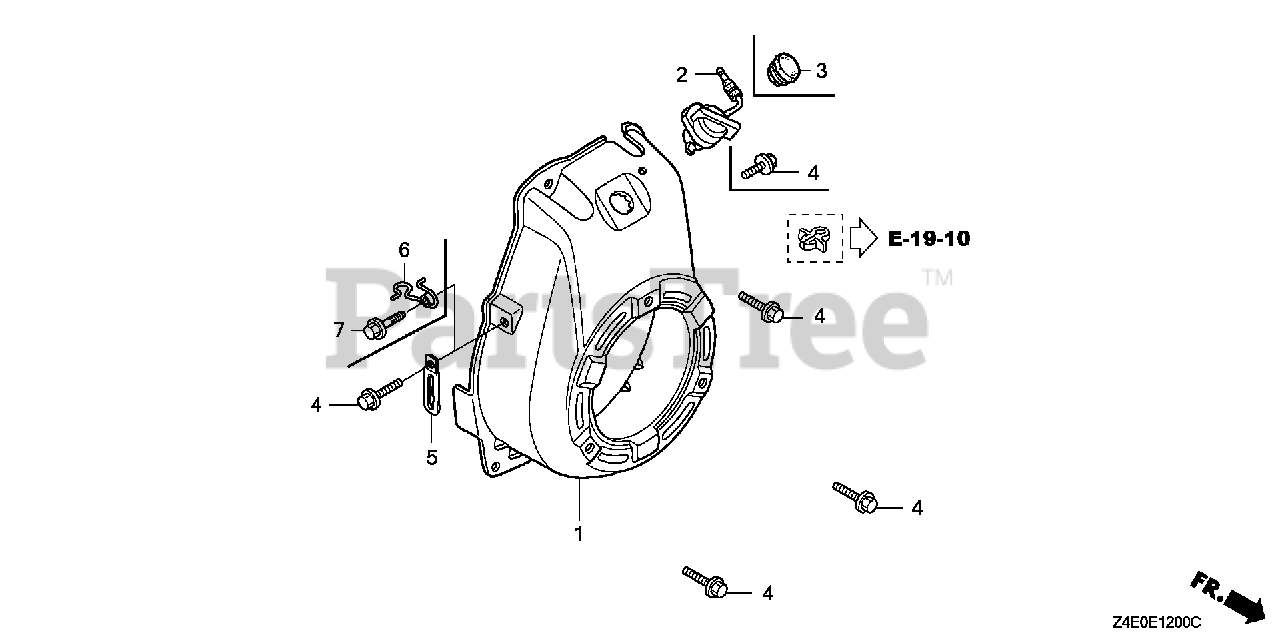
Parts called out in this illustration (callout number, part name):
1	COVER, FAN *R280* (POWER RED)
2	SWITCH ASSY., ENGINE STOP
4	BOLT, FLANGE (6X14)
